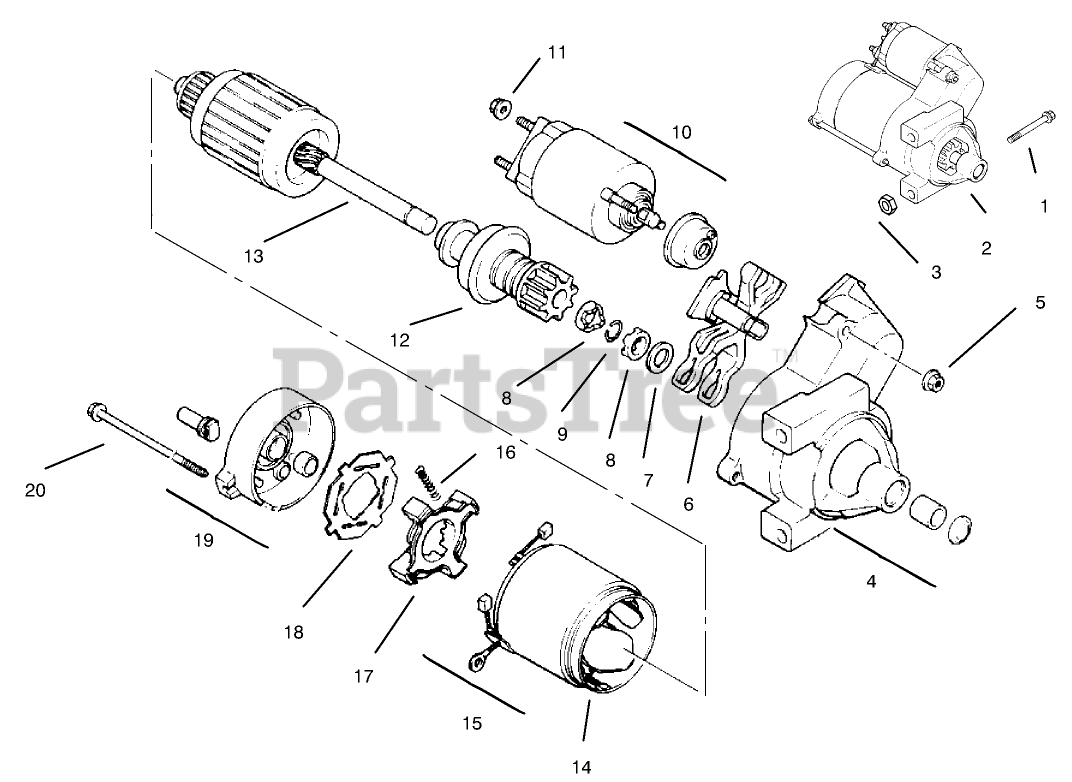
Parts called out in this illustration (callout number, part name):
2	Starter-Solenoid Shift (Incl. Ref. #4-20)
4	Cap-End, Drive
5	Nut-Starter
6	LEVER-DRIVE, STARTER
7	Washer-Thrust
8	Nut-Stop Collar
9	Ring-Retainer
12	Drive-Pinion
13	Armature-Starter
14	Frame w/Brushes ASM
15	Kit-Brush (Incl. Ref. #16)
16	Spring-Brush
17	Holder-Brush
18	Insulator
19	CAP-END, COMMUTATOR
20	Bolt-Thru
